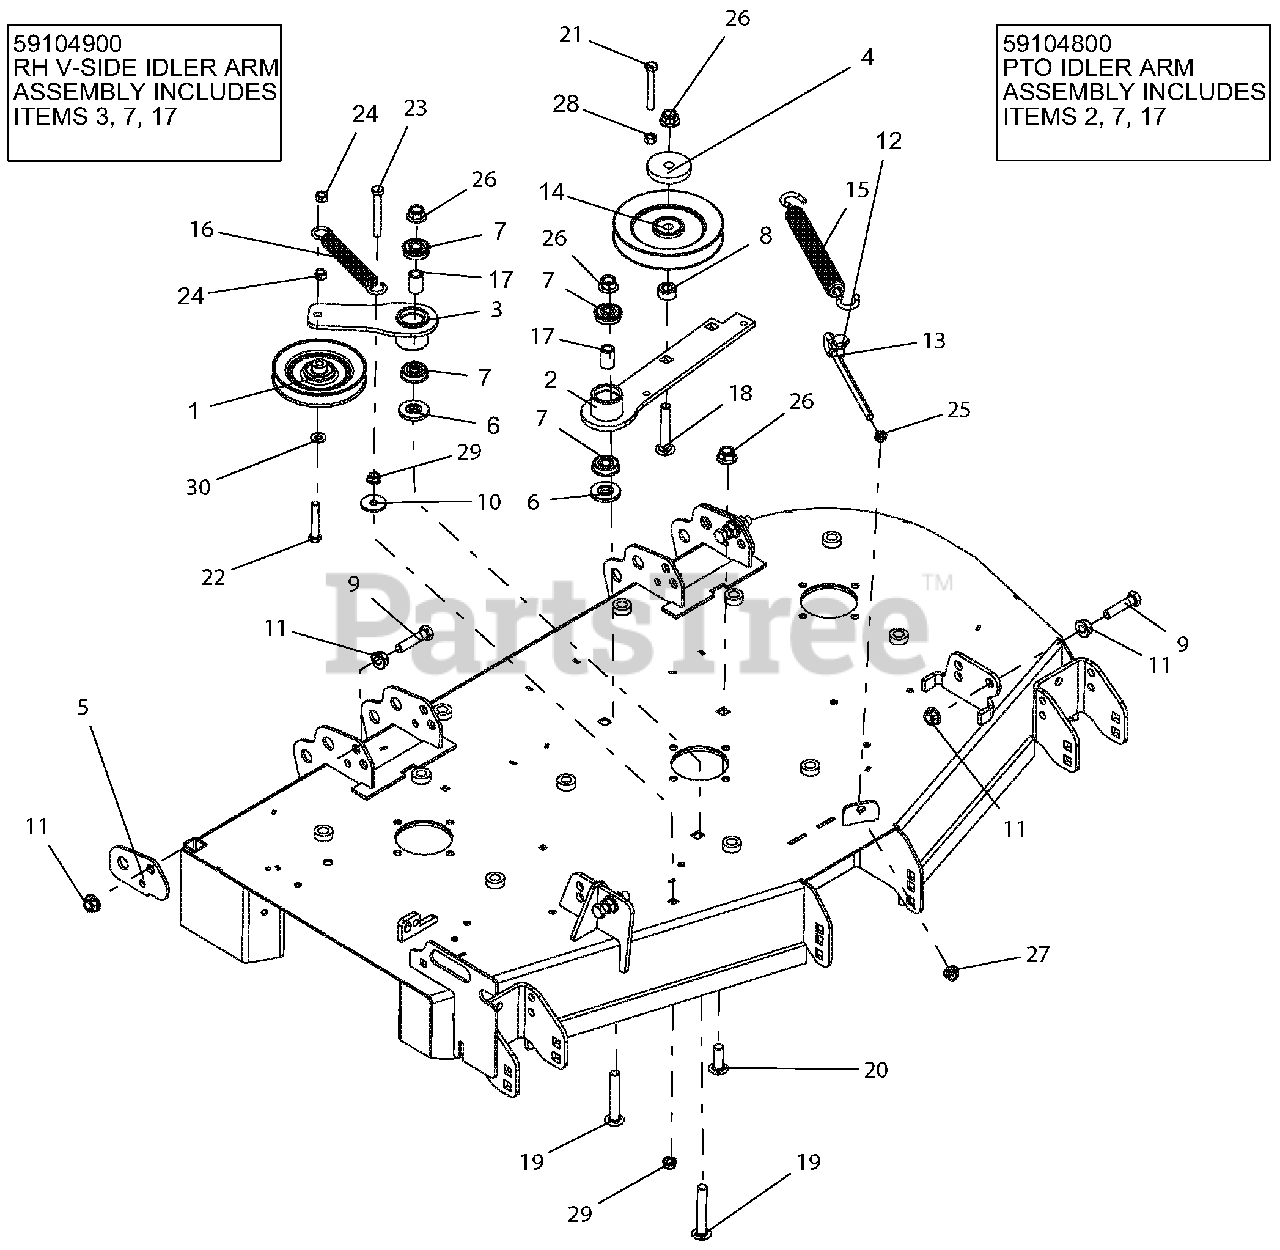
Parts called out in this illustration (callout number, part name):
1	IDLER, V-5.00" W/.69 STANDOFF
2	WLDMT, DECK PTO IDLER ARM-BLACK
3	WLDMT, DECK RH IDLER ARM-BLACK
4	CAP, IDLER BEARING SEALING
5	PLATE, PT REAR CHAIN MTG DOUBLER-RED
6	SPACER, IDLER ARM
7	BRG, BALL .501 X 1.38 X .438 SEALED
8	BSHG, SPCR .502 X .997.50 PM
9	BLT, HEX M12-1.75X50 CLS8.8 YZ
10	WSHR-FL-STL .406X1.375X.135 YZ
11	NUT, SPLK -FLG M12-1.75 YZ
12	BLT, SHLDR EP .38-16X.30 HEX YZ
13	BOLT, .38-16X6.00 .62 DIA EYE
14	SHEAVE, .50" ID X 6.00" OD V-IDLER
15	SPRG, EXTENSION
16	SPRG, EXTENSION
17	SPACER, .510 X .750 X 1.148
18	BLT-RDHDSQNK .50-13X3.00YG5
19	BLT-RDHDSQSHNK .50-13X3.25 YWZC
20	BLT-RDHDSQSHNK .50-13X1.50 YWZC
21	BLT-HEX .38-16X2.75 GR5 YWZC
22	BLT-HEX .38-16X2.25 GR5 YWZC
23	BLT-HEX .38-16X3.00 GR5 YWZC
24	NUT-LK-CTR .38-16 YWZC
25	NUT, JAM .375-16 YWZC
26	NUT-LK-NYL-FLG .50-13 YWZC
27	NUT-LK-NYL-FLG .38-16 YWZC
28	NUT-HEX .38-16 YWZC
29	@NUT-SPNLK-FLG .375-16 YWZC
30	WSHR-FL-STL.406X.812X.065 YWZ
